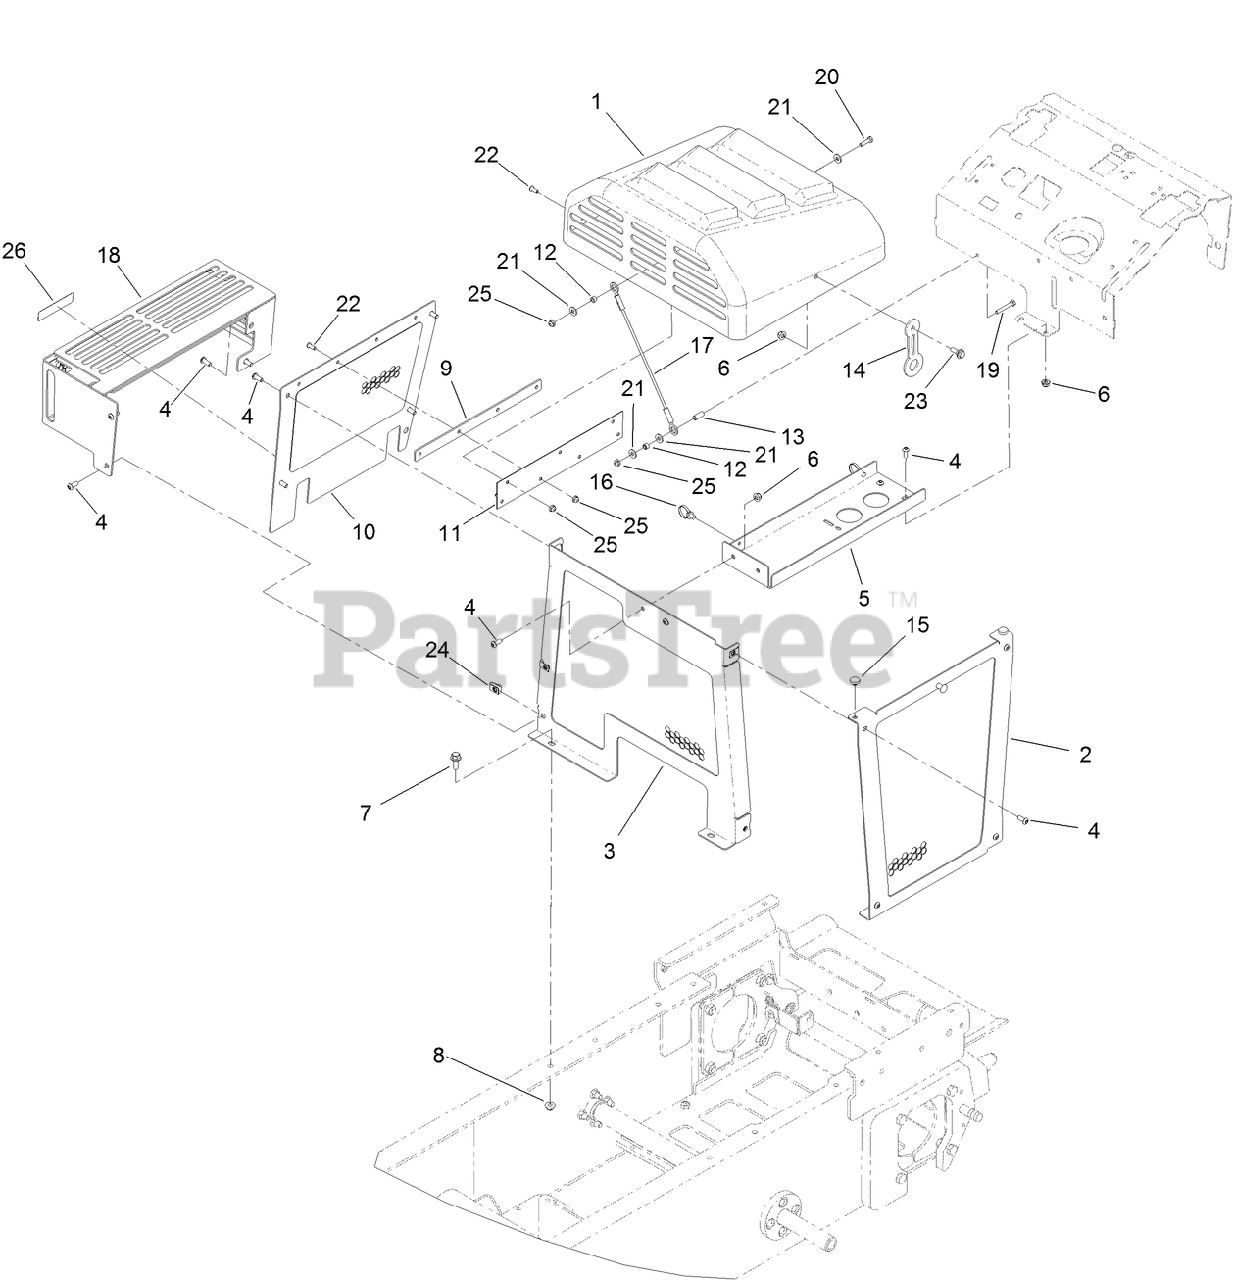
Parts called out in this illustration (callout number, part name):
1	HOOD ASM
2	PANEL-SIDE, LH
3	PANEL-FRONT
4	SCREW-HSBH
5	PLATFORM-BATTERY
6	NUT-HF, NI
7	SCREW-HHF
8	NUT-HF, NI
9	PLATE-SPACER, HOOD
10	PANEL-SIDE, UPPER
11	HINGE-HOOD
12	SPACER-BLADE, ROTOR
13	SPACER-BRAKE, PARKING
14	LATCH-RUBBER
15	BUMPER
16	CLIP-TIE
17	LANYARD
18	GUARD-MUFFLER
19	SCREW-HH
20	SCREW-HHF
21	WASHER-FLAT
22	SCREW-HSBH
23	SCREW-SHOULDER
24	NUT-CLIP, U
25	NUT-HF
26	DECAL-ARRESTER, SPARK
